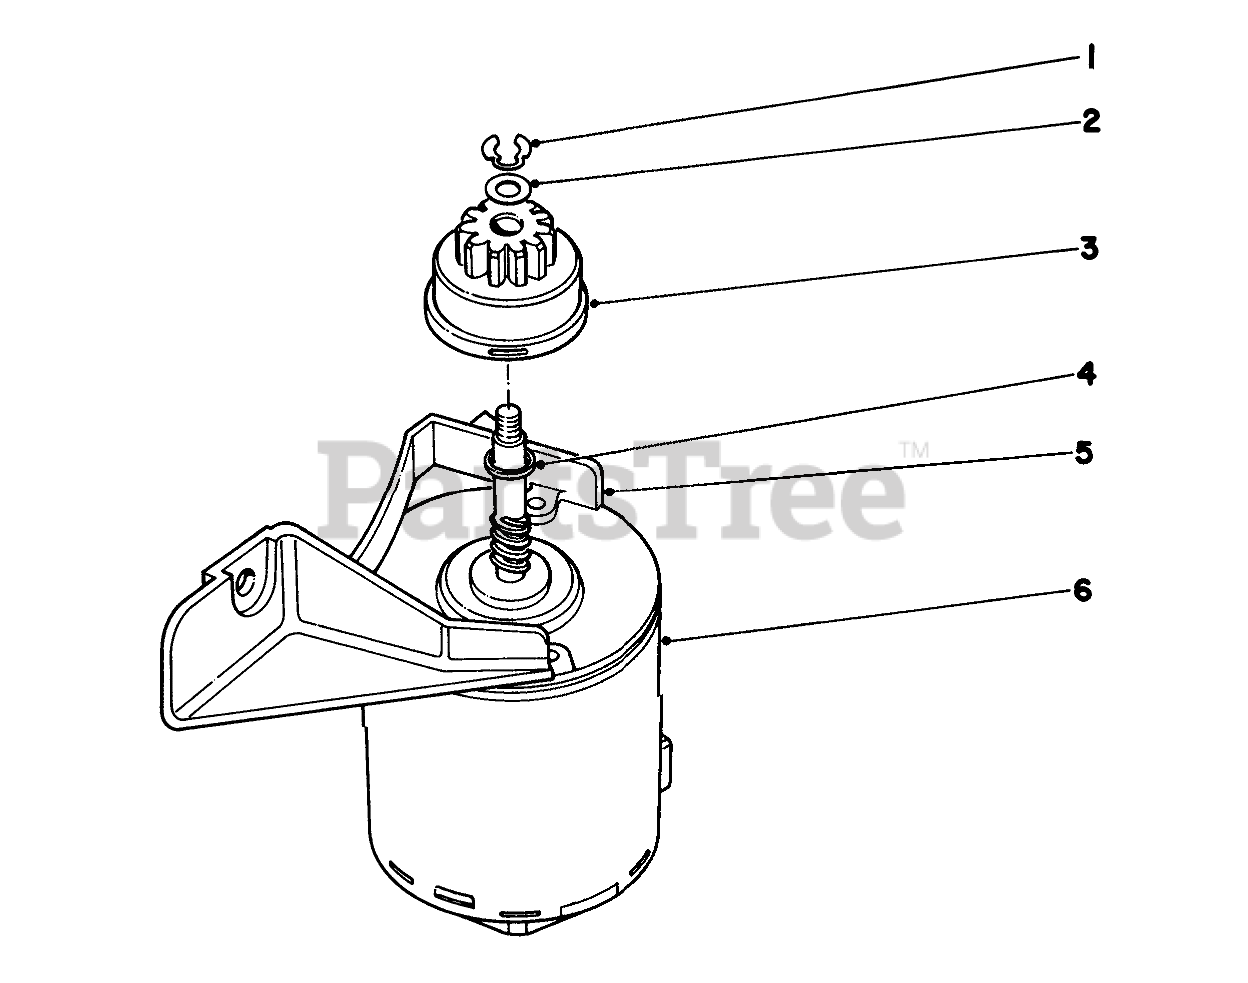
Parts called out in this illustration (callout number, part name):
1	RING-RETAINING
2	WASHER
3	PINION ASM
4	Spacer
5	Mounting Bracket
6	Starter Motor
